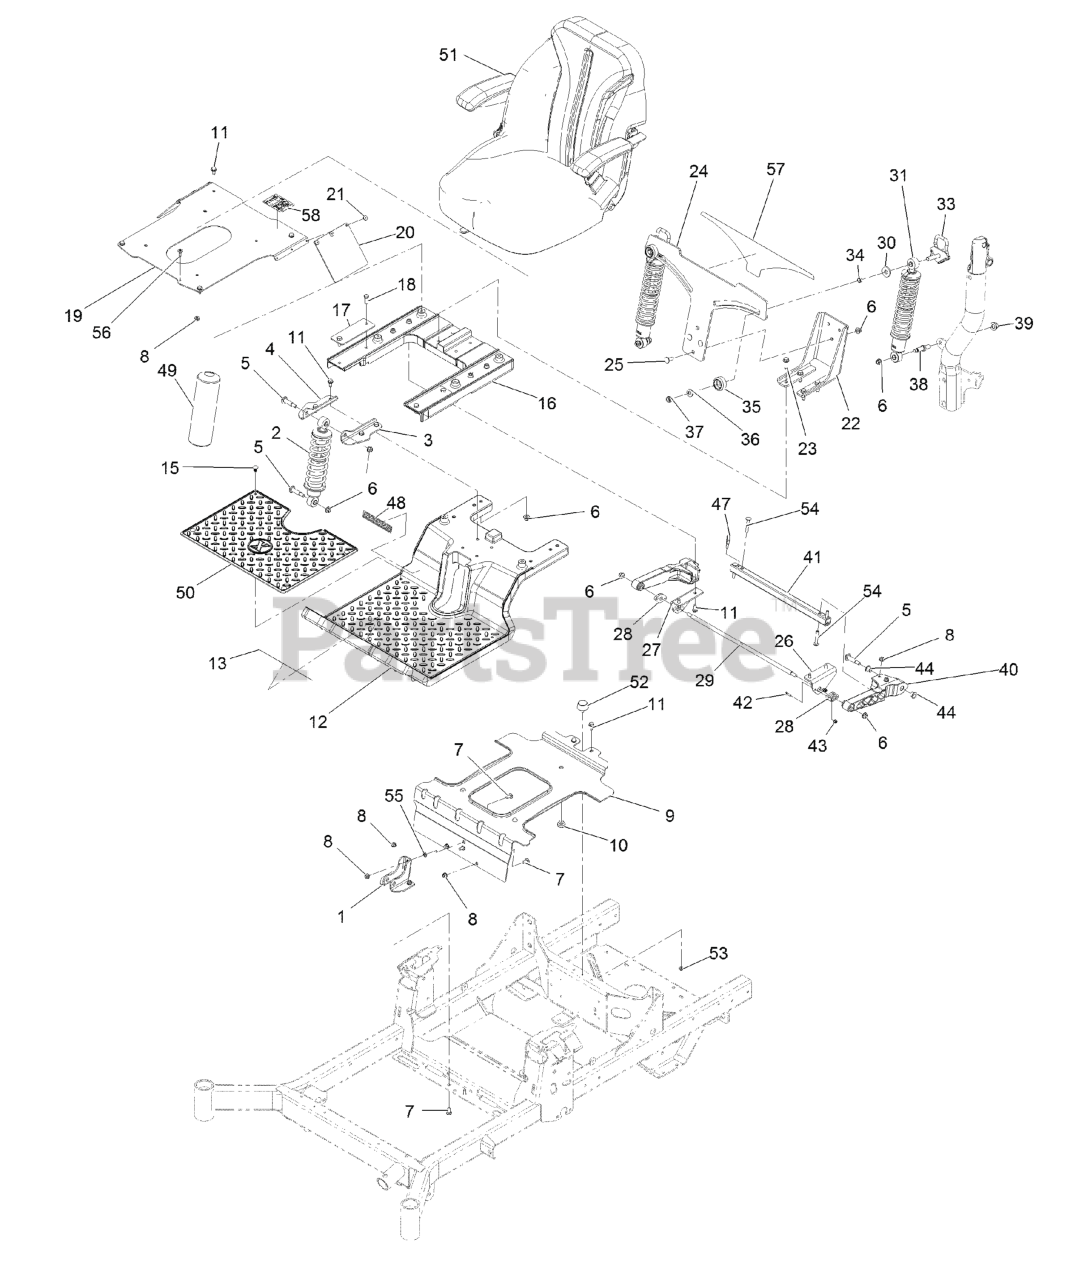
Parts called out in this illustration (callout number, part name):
1	BRACKET-SHOCK, FRONT LOWE
2	SHOCK/SPRING
3	BRACKET-SHOCK MOUNT, UPPE
4	BRACKET-SHOCK MOUNT, UPPE
5	BOLT-SHOULDER, HWH
6	NUT-HF, NI
7	SCREW-CARR
8	NUT-HF, NI
9	BRACKET-TANK
10	BUMPER-SEAT
11	Screw-HWH 5/16-18 X 3/4 Tf
12	SUBFRAME-FRONT
13	DECAL-DANGER
15	PLUG-PLASTIC
16	SUBFRAME-REAR
17	PLATE-BACKER
18	SCREW-HH
19	PLATE-SEAT
20	FLAP-RUBBER
21	RIVET-POP
22	BRACKET-MOUNT, LOWER
23	SCREW-THD
24	PLATE-MOUNTING, ADJ SHOCK
25	SCREW-CARR
26	BRACKET-ARM, TRAILING (LH
27	BRACKET-ARM, TRAILING (RH
28	BEARING-FLANGE
29	ROD-PIVOT
30	WASHER-PLASTIC
31	SHOCK/SPRING ASM
33	CAM LOCK ASM
34	BEARING-SLEEVE
35	KNOB-LOCK, CAM
36	WASHER-ADJUSTING
37	NUT-HEX
38	BOLT-SHOULDER
39	Nut-Lock 1/2-13
40	TRAILING ARM
41	TUBE-ARM, TRAILING
42	SCREW-CARR
44	BUSHING-FLANGE
47	CLAMP-HOSE
48	DECAL-RADIUS LOGO
49	COVER-SHOCK
50	FLOOR MAT
51	ASM-SEAT EXMARK
54	BOLT-CARR
55	NUT-PUSH
56	SCREW-SHOULDER
57	DECAL-ADJUSTMENT, RIDE
58	DECAL-AID, SERVICE
